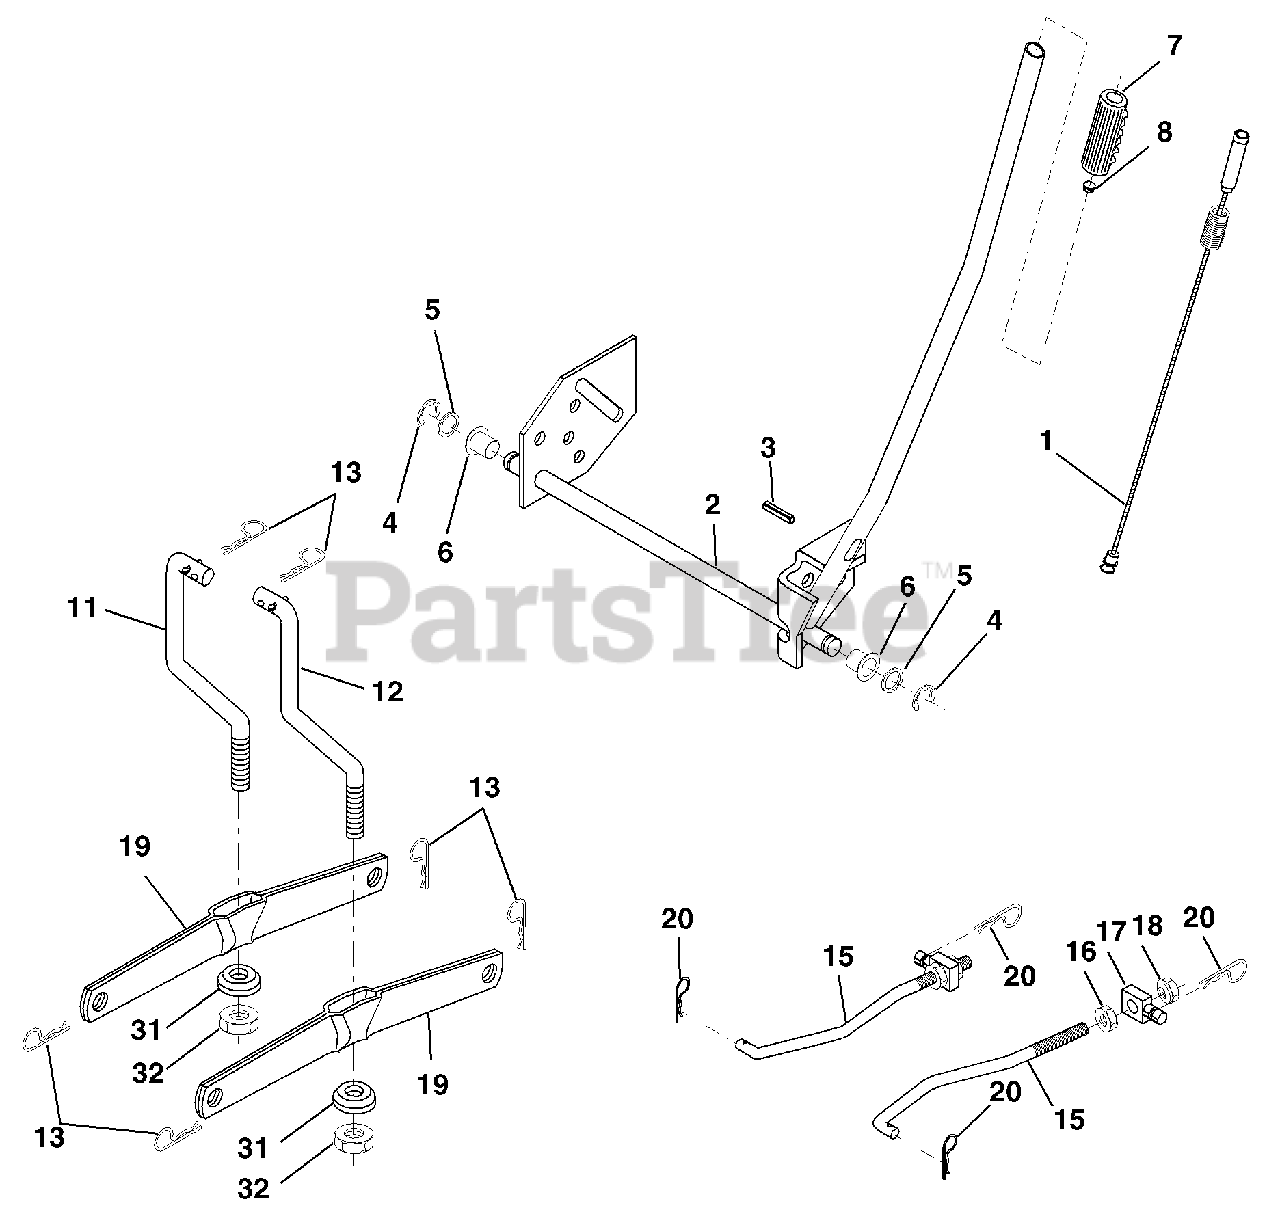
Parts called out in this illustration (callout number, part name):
1	Washer Asm Inner Spring W/Plunger
2	Shaft Asm. Lift
3	Pin Groove
4	E Ring #5133-62
5	Washer 21/32 x 1 x 21 Ga.
6	Bearing Nylong
7	Grip Handle Fluted
8	Button Plunger
11	Link Asm Lift L.H.
12	Link Asm Lift R.H.
13	Retainer Spring
15	Link Front
16	Nut Jam Hex 1/2-13 Unc
17	Trunnion Blk Zinc
18	Nut Lock w/Wsh 1/2-13 Unc
19	Arm Suspension Mower
20	Retainer Spring
31	Bearing, Pvt. Lift
32	Nut Crownlock 3/8-24
